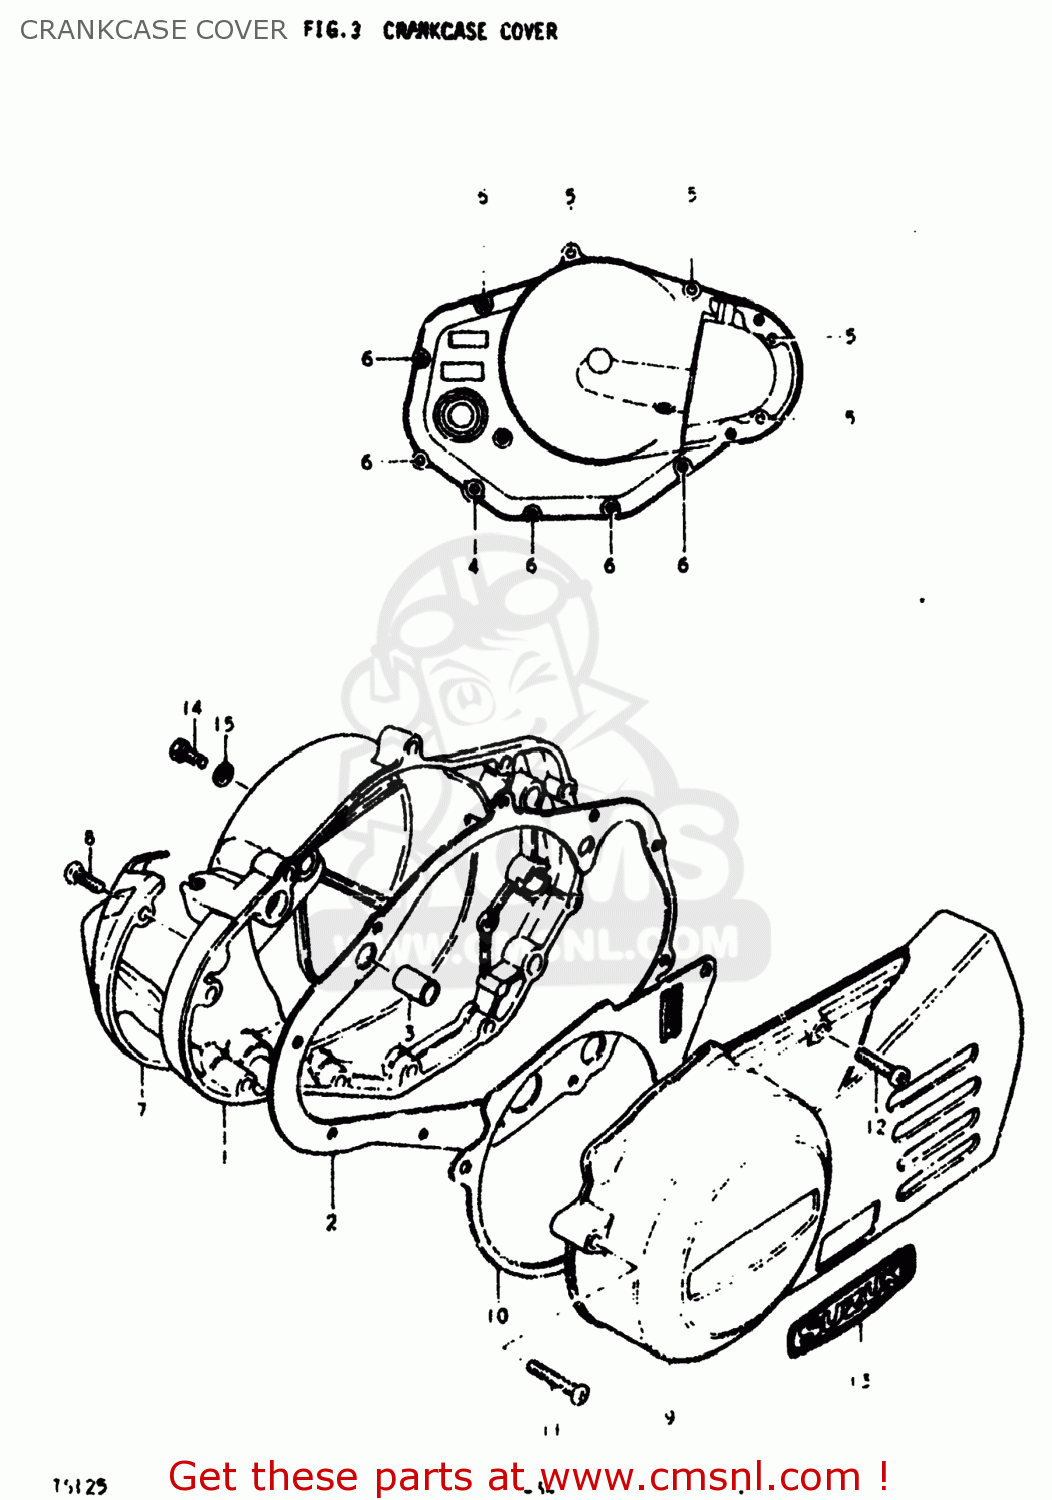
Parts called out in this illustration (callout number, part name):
1	COVER,CLUTCH
2	GASKET,CLUTCH COVER (MCA)
3	PIN
4	SCREW (6X45)
5	SCREW
6	SCREW
7	COVER,CLUTCH RELEASE ARM
8	SCREW
9	COVER,MAGNETO
10	GASKET,MAGNETO COVER (NAS)
11	SCREW
12	SCREW
13	EMBLEM,GENERATOR COVER
14	SCREW(6X10)
15	GASKET(6.2X11X1) (NAS)
